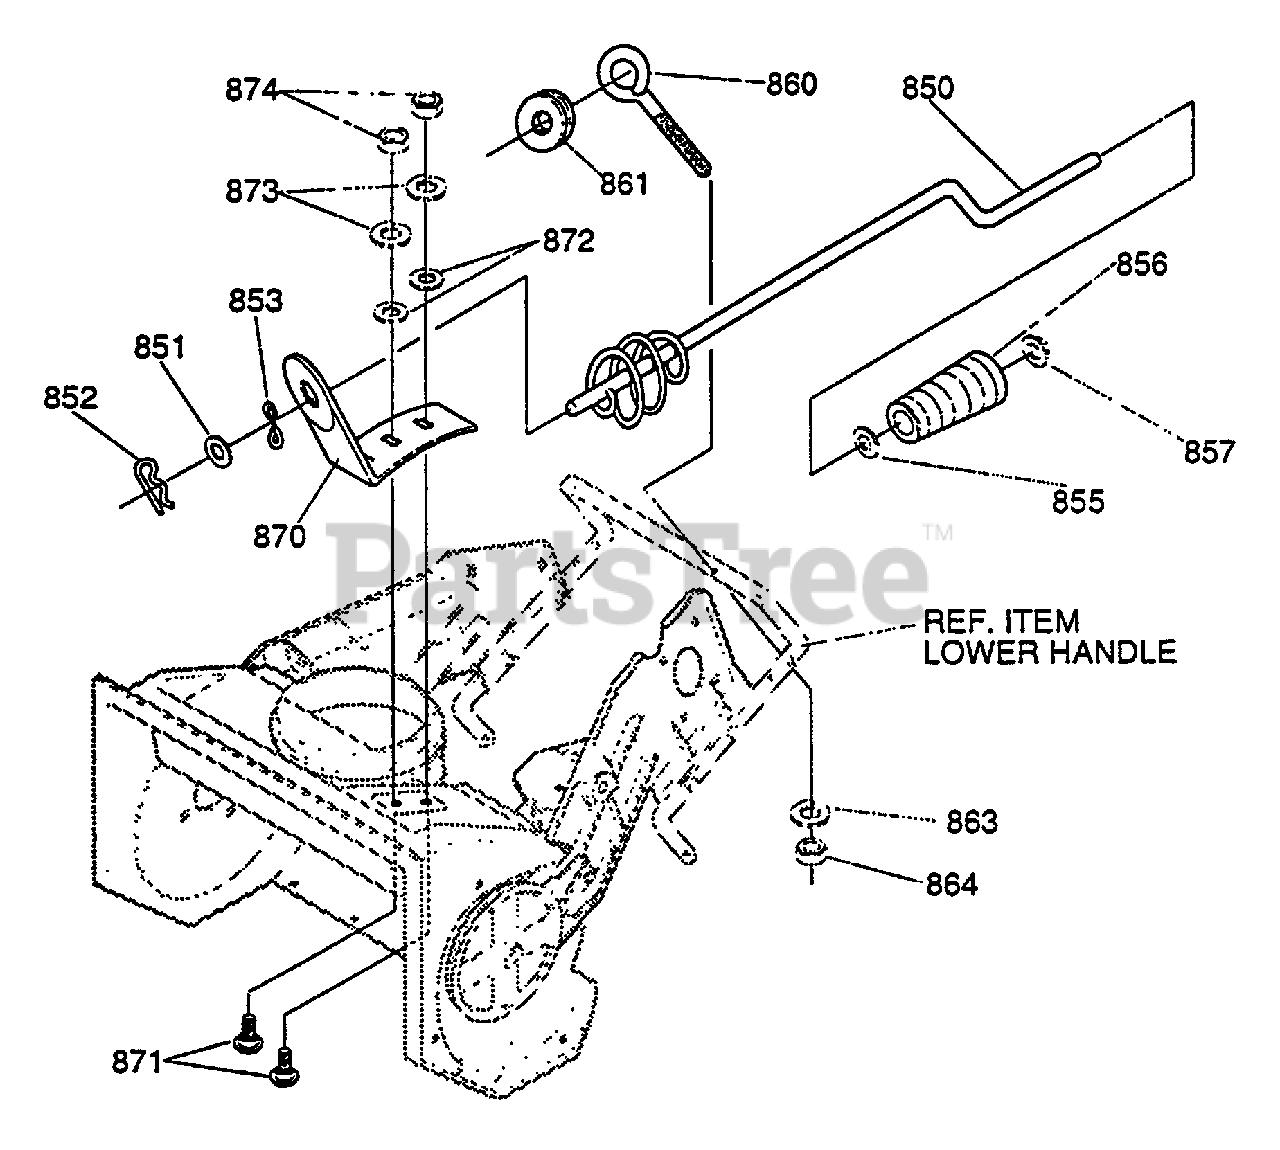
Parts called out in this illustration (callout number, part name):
850	ROD, ASSY UPR CHUTE CTRL
851	FLATWASHER .406 X .81 X .065
852	PIN, COTTER
853	WASHER, CURVED SPRING
855	FLATWASHER .406 X .81 X .065
856	KNOB, SLEEVE
857	CAP NUT, PUSH-ON
861	GROMMET, EYE BOLT
863	WASHER, REG SPTLK
864	NUT, 3/8-16
870	BRACKET, CHUTE ROTATE
871	BOLT, 5/16-18 X .75
872	WASHER, FLAT
873	WASHER, HVSPTLK
874	NUT, 5/16-18 REG HEX CTRLK
